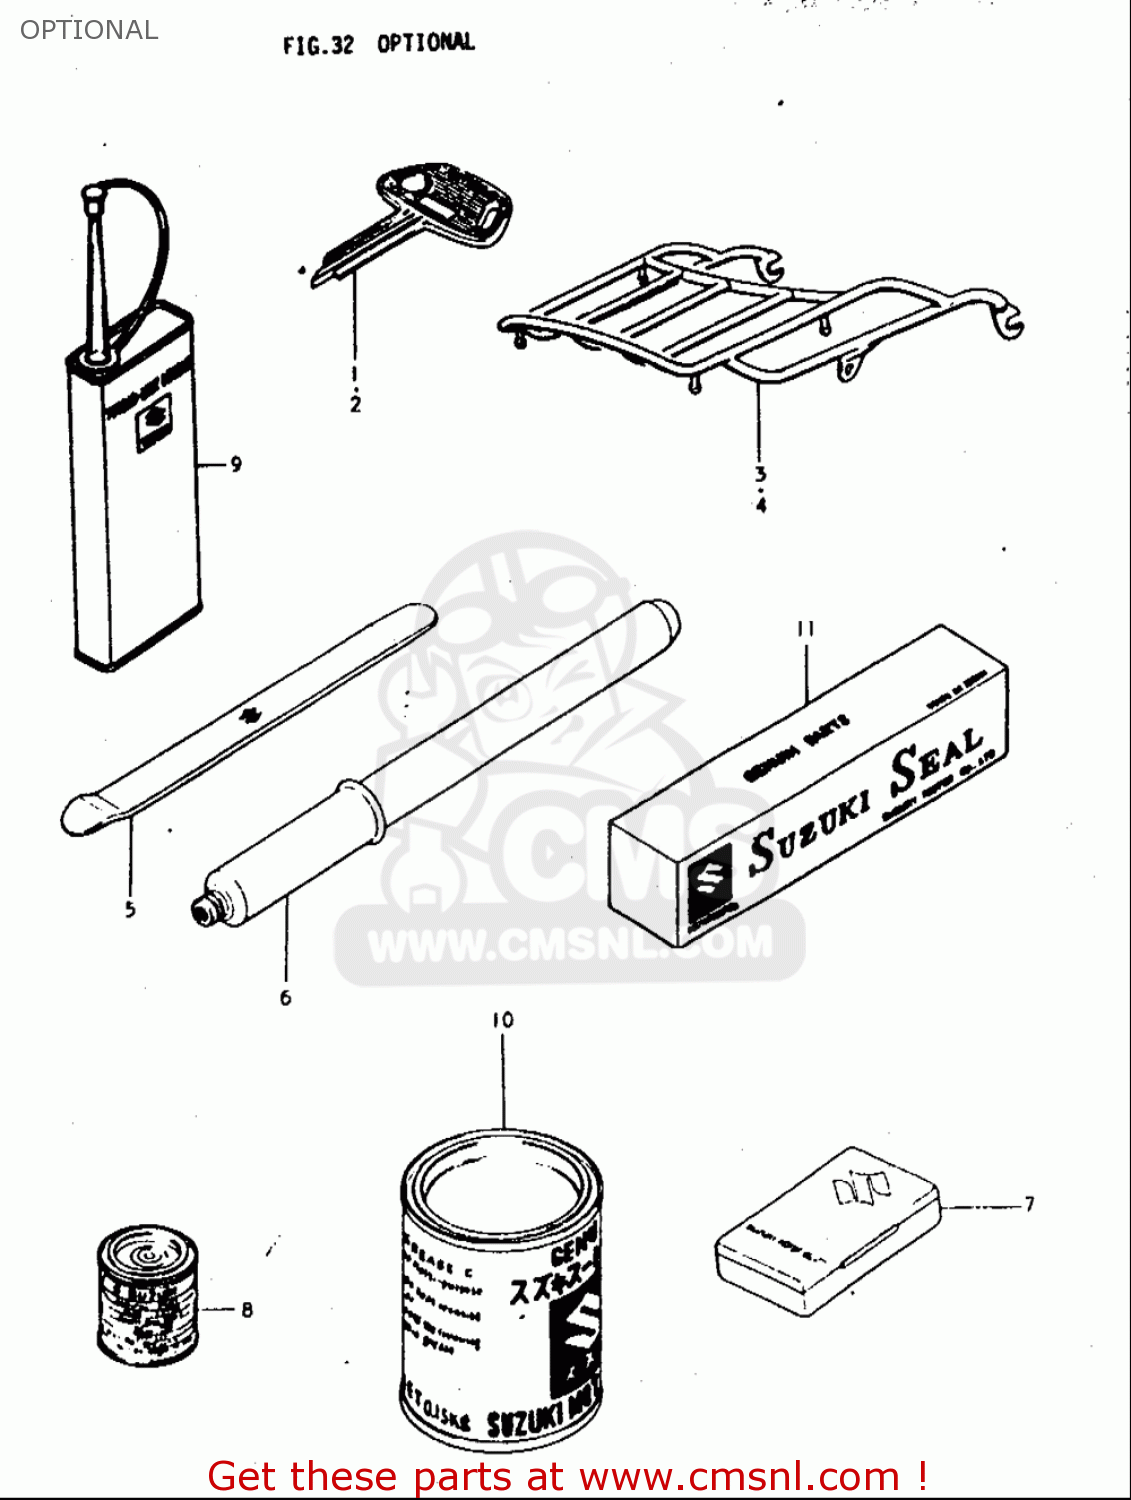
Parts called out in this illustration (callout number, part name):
5	LEVER,TIRE
9	THREAD LOCK NO.1401 CLEAR 200G
10	GREASE(C)EP2 LITHIUM 150G
